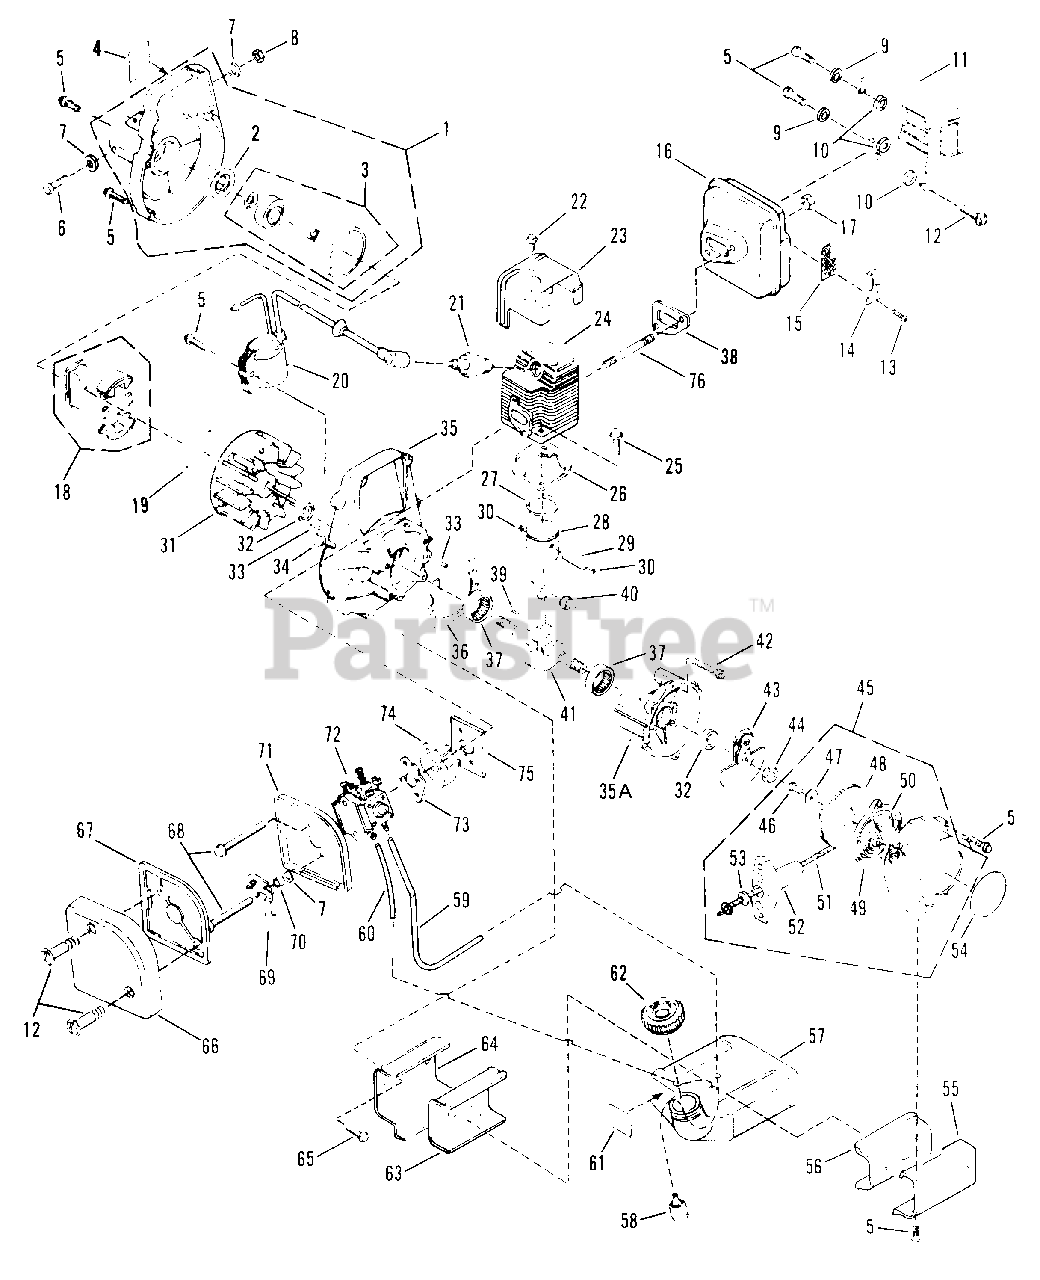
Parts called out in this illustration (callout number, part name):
1	HOUSING ASSM'Y., Fan
2	PLATE, Thrust
3	DRUM ASSM'Y., Clutch
4	DECAL, Engine
5	SCREW, M4 x 18.50mm
6	SCREW, M5 x 35mm
7	WASHER, Flat, M5
8	NUT, Hex, M5
9	WASHER, Flat, M4
10	SPACER, Muffler
11	SHIELD, Muffler
12	SCREW, M4 x 25mm
13	SCREW, #5-20 x 7/16"
14	COVER, Spark Arrestor
15	SCREEN, Spark Arrestor
16	MUFFLER ASSEMBLY
17	NUT, Flange, M5
18	CLUTCH ASSM'Y.
19	PLATE, Side
20	COIL, Ignition
22	SCREW, M5 x 8.5mm P.H.
23	COVER, Cylinder
24	CYLINDER
25	SCREW, M6 x 18mm P.H.
26	GASKET, Cylinder
27	RING, Piston
29	PIN, Piston
30	SNAP-RING, Piston Pin
31	FLYWHEEL
32	SEAL, Oil
34	GROMMET
35	CRANKCASE ASSM'Y.
36	GASKET, Crankcase
37	BEARING, Crankshaft
38	GASKET, Muffler
39	KEY, Woodruff
40	BEARING, Needle
41	CRANKSHAFT ASSEMBLY
42	SCREW, M5 x 28.5mm P.H.
43	RATCHET ASSEMBLY
44	NUT, Hex, M8
45	STARTER ASSM'Y.
46	SCREW, M4 x 9.50mm P.H.
47	WASHER, Flat, M4
48	DRUM/ROPE ASSM'Y.,
49	SPRING, Starter
50	GUIDE, Rope
51	ROPE, Starter
52	HANDLE, Starter
53	WASHER, Nylon
54	DECAL, Starting instruction
55	BRACKET, Fuel Tank
56	CUSHION, Fuel Tank
57	TANK ASSM'Y, Fuel
58	PICK-UP, Hose
59	HOSE, Fuel Pick-up
60	HOSE, Fuel Return
61	DECAL, 32:1 Fuel/Oil Mix Ratio
62	CAP, Fuel
63	CUSHION, Bracket
64	BRACKET ASSM'Y., Tank/Shield
65	SCREEN, M4 x 8mm
66	COVER, Air Filler
67	FILTER, Air
68	SCREW, M5 x 55mm
69	SHUTTER, Choke (Assembly)
70	SPACER, Choke Shutter
71	AIR-BOX/GROMMMET ASSM'Y
72	CARBURETOR ASSM'Y
73	GASKET, Carburetor
74	INSULATOR, Carburetor
75	GASKET Insulator
76	STUD BOLT
